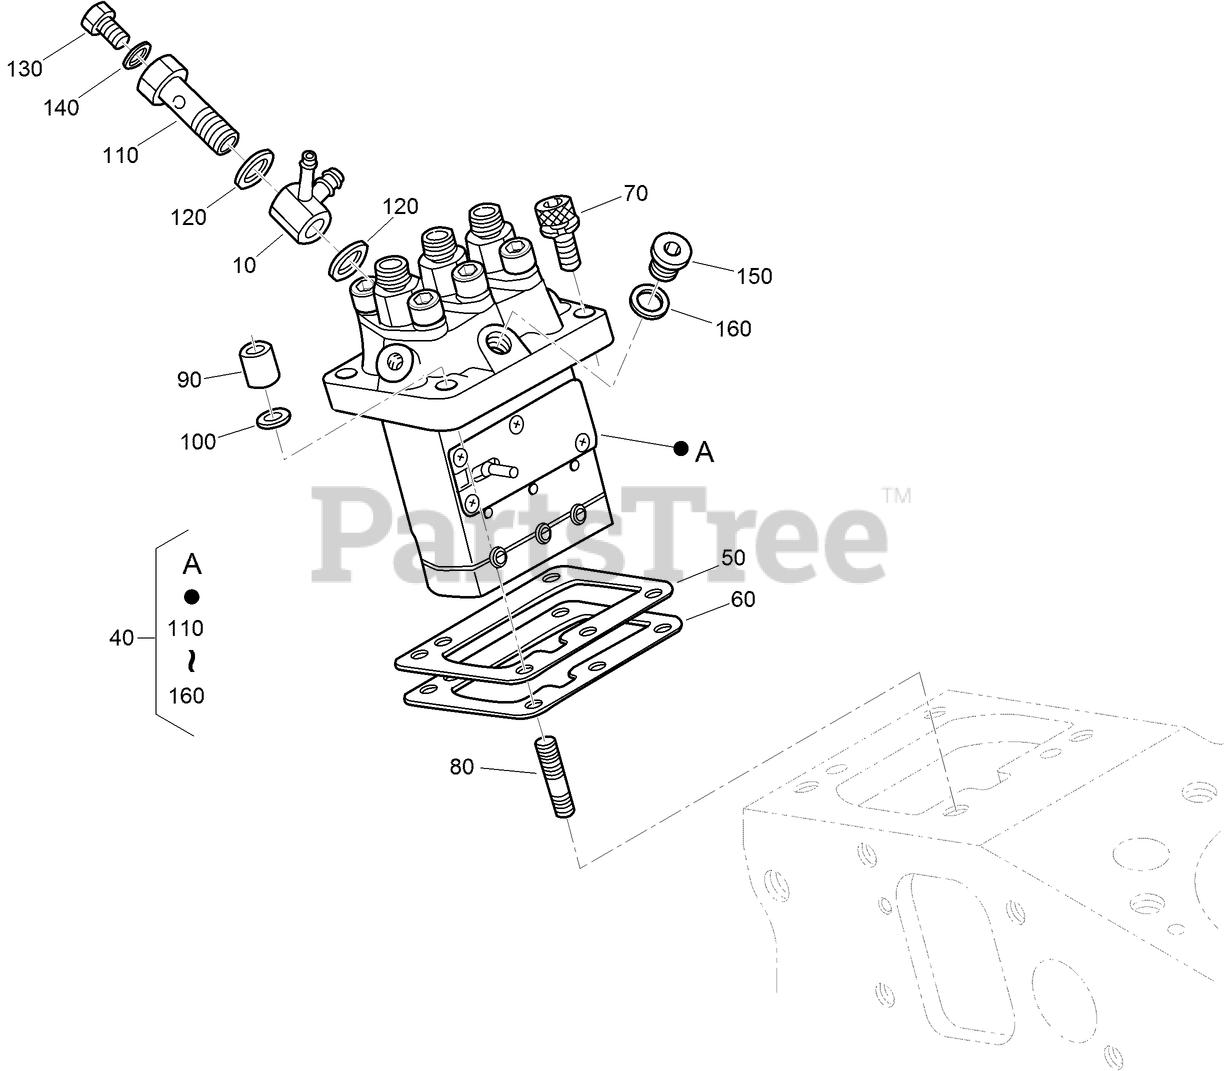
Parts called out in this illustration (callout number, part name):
40	INJECTION PUMP ASM
50	SHIM-INJECTION (0.175MM)
50	SHIM-INJECTION (0.20MM)
50	SHIM-INJECTION (0.25MM)
60	SHIM-INJECTION (0.30MM)
60	SHIM-INJECTION (0.35MM)
70	BOLT-HEX SOC HD
90	NUT-CAP
100	WASHER-SPRING
110	SCREW-HOLLOW
120	GASKET
130	SCREW
140	GASKET
160	GASKET
